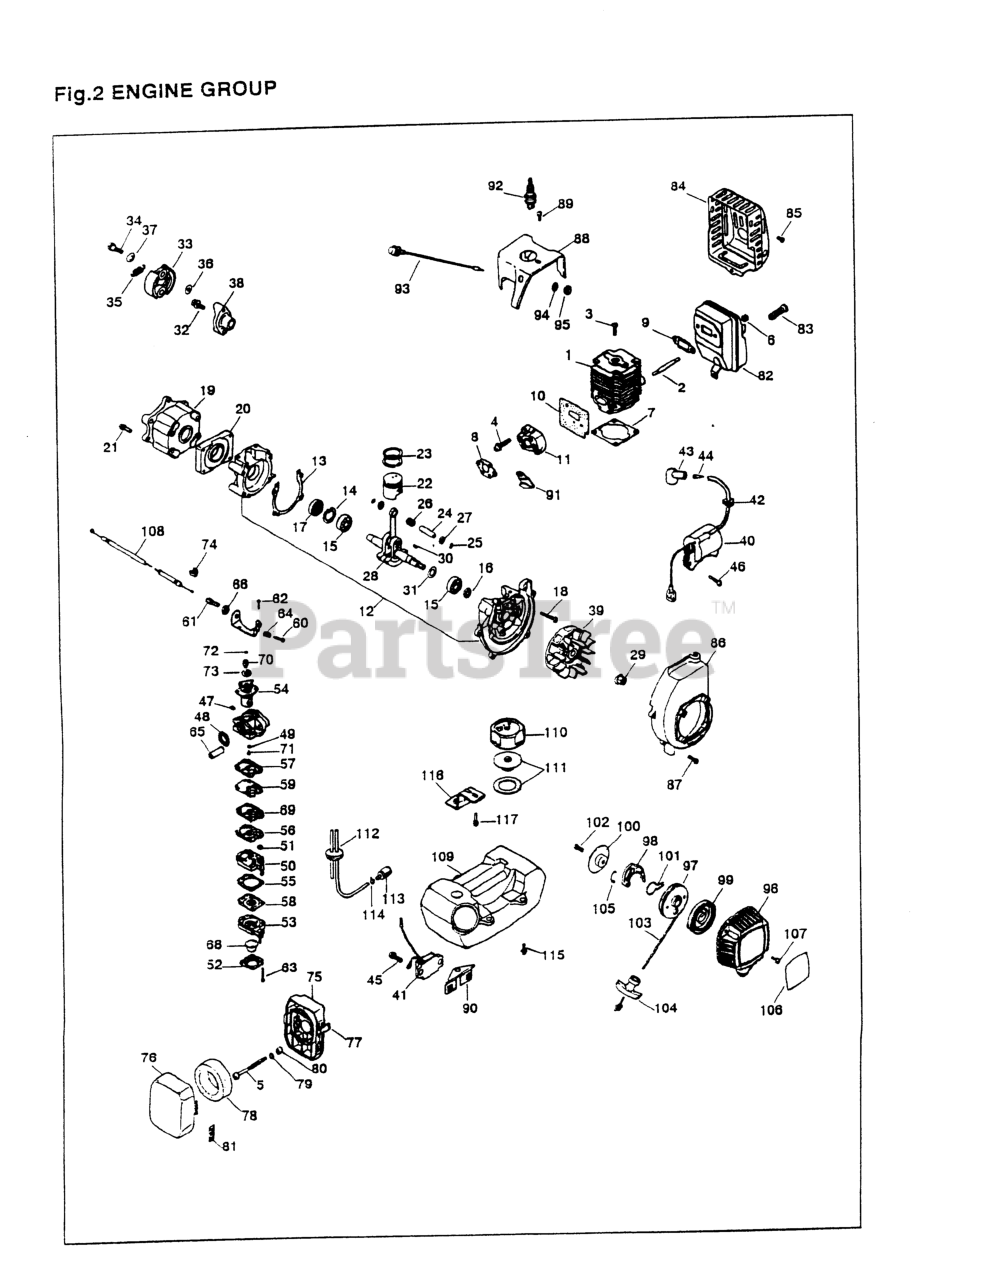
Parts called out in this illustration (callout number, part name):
1	CYLINDER-C
2	STUD
3	SCREW, M5 X 16
6	NUT
11	INSULATOR
12	CRANKCASE
14	RING, SNAP, M28 x 1.2
15	BEARING
16	SEAL, OIL
17	SEAL, OIL (RPLS 1140-21220)
18	SCREW, M5 x 30(RPLS 0263-00530
19	CASE, CLUTCH
22	PISTON (USE 5600-41111)
23	RING, PISTON (RPLS 1850-41210)
24	PIN, PISTON 5x8x26
25	RING, SNAP (RPLS 1101-41320)
27	WASHER
28	CRANKSHAFT
30	KEY
32	BOLT, M6 x 14(RPLS 0224-00614)
34	BOLT
36	WASHER, FLAT (USE 182303)
37	WASHER (RPLS -51241)
38	PLATE, CLUTCH
41	UNIT
44	SPRING
45	SCREW, M5 X 12
46	SCREW, M4 x 20
47	RING
48	RING, PACKING (NLA)
49	RING, O
50	KIT ONLY
51	SCREEN
52	COVER
53	BODY
54	VALVE, THROTTLE
55	KIT ONLY
56	GASKET, PLATE
57	GASKET, PUMP
58	DIAPHRAGM (USE 4810-81260)
59	DIAPHRAGM
60	SCREW, IDLE AD
62	SCREW
63	SCREW
64	SPRING, IDLE A
65	SLEEVE, MOUNT
66	NUT, CABLE ADJUSTER
68	PUMP, PRIMING
69	PLATE, PUMP (NLA)
70	SWIVEL (USE -06040)
72	PLUG NEEDLE
73	WASHER
74	CAP, CABLE END
75	BODY
76	COVER
80	SLEEVE (USE 1918-82170)
81	LABEL
83	ARRESTER (RPLS 5850-15140)
86	COVER (REPLACES -31101)
87	SCREW, M4 x 14
88	COVER, CYLINDER
90	BRACKET (RPLS -72240)
91	CLAMP
93	SWITCH ASSY (RPLS -72200)
94	WASHER
95	NUT
96	STARTER ASSEMBLY
98	RATCHET
100	PLATE (NLA) (RPLS -75240)
101	SPRING, FRICTION
102	SCREW (USE -75261)
104	KNOB
105	SPRING
107	SCREW, M4 X 12
111	VALVE COMPLETE
113	5500-85400 (RRLS. 1750-85300)
114	CLIP (REPLACES 2841-31280)
116	BRACKET-NO LONGER AVAILABLE
NI	CARBURETOR-A (NLA)
NI	BRACKET, IDLE
NI	CLEANER ASSEMBLY
NI	MUFFLER ASSEMBLY
